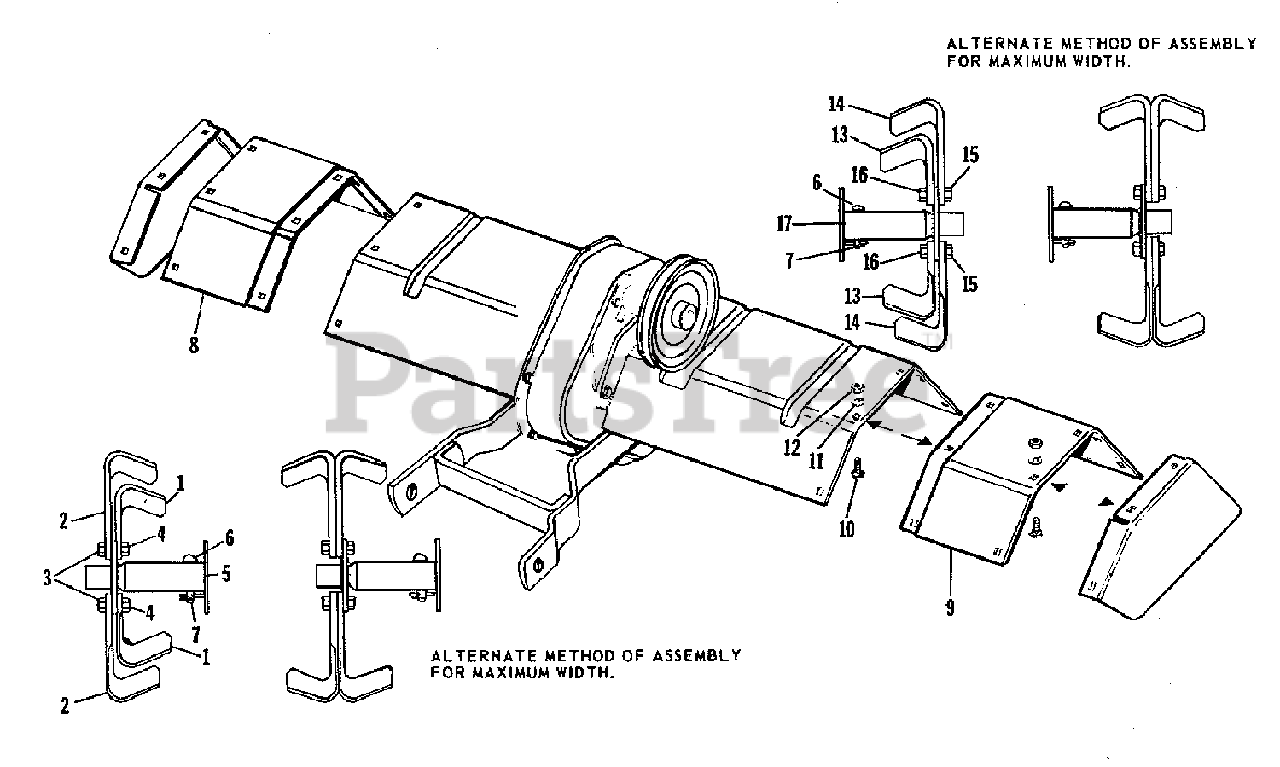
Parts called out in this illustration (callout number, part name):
1	HANDLE, Clutch
2	CLIP, Spring
3	WASHER, Flat, 3/8
4	SCREW, Hex Cap, 7/16-14 x 1-1/4
7	NUT, Hex Lock, 7/16-14
9	LEVER, Clutch
10	NUT, Hex, 3/8-16
11	WASHER, Lock, 3/8
12	NUT, Whiz Lock, 5/16-18
13	SUPPORT, Rear Belt Guard
14	WASHER, Flat, 7/16
15	SCREW, Hex Cap, 7/16-14 x 3-1/2
17	BOLT, Carriage, 5/16-18 x 1/2
21	SCREW, Hex Cap, 3/8-16 x 1-1/4
22	WASHER, Flat, 5/16
23	PULLEY, Idler
24	PULLEY, Idler
28	WASHER, Flat, 1/2
30	SCREW, Hex Cap, 1/2-13 x 5
31	SCREW, Hex Cap, 3/8-16 x 4-1/2
33	CLIP, Spring
35	NUT, Hex Lock, 3/8-16
36	NUT, Hex Lock, 1/2-13
40	SCREW, Hex Cap, 3/8-16 x 7/8
41	BRACKET, Depth Limit
43	CLIP, Spring
45	NUT, Hex Lock, 5/16-18
50	SCREW, Set, 1/4-20 x 3/8"
54	SCREW, Hex, 3/8-16 x 1
55	SCREW, Hex, 7/16 x 14 x 1-1/4
56	WASHER, Lock, 7/16
